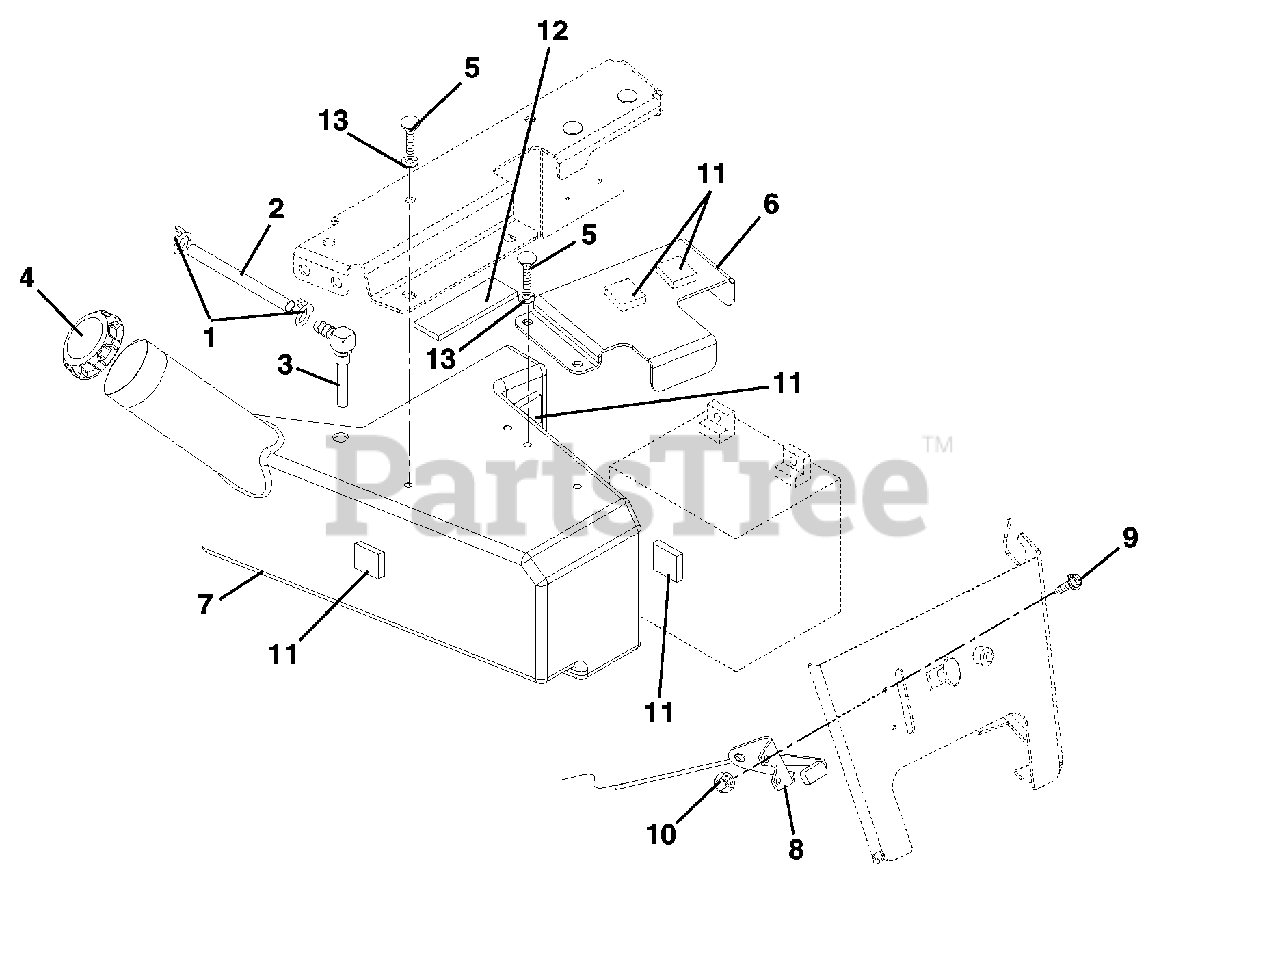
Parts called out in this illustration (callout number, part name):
1	CLAMP-HOSE WIRE .490/.510X.116
2	GAS LINE-BULK 1/4" I.D.
3	TANK FITTING
4	FUEL CAP
5	BLT-SERHFWH .25-20X.75 YWZC
6	BRACKET-BATTERY
7	TANK-FUEL
8	THROTTLE CABLE
9	@SCR-MCH 10-24X.50 HWH YWZC
10	@NUT-LK-NYL 10-24 W/INSRT YWZC
11	PAD, FOAM
12	VHB TAPE 4941F
13	@WSHR-LK .31X.078 REG YWZC
